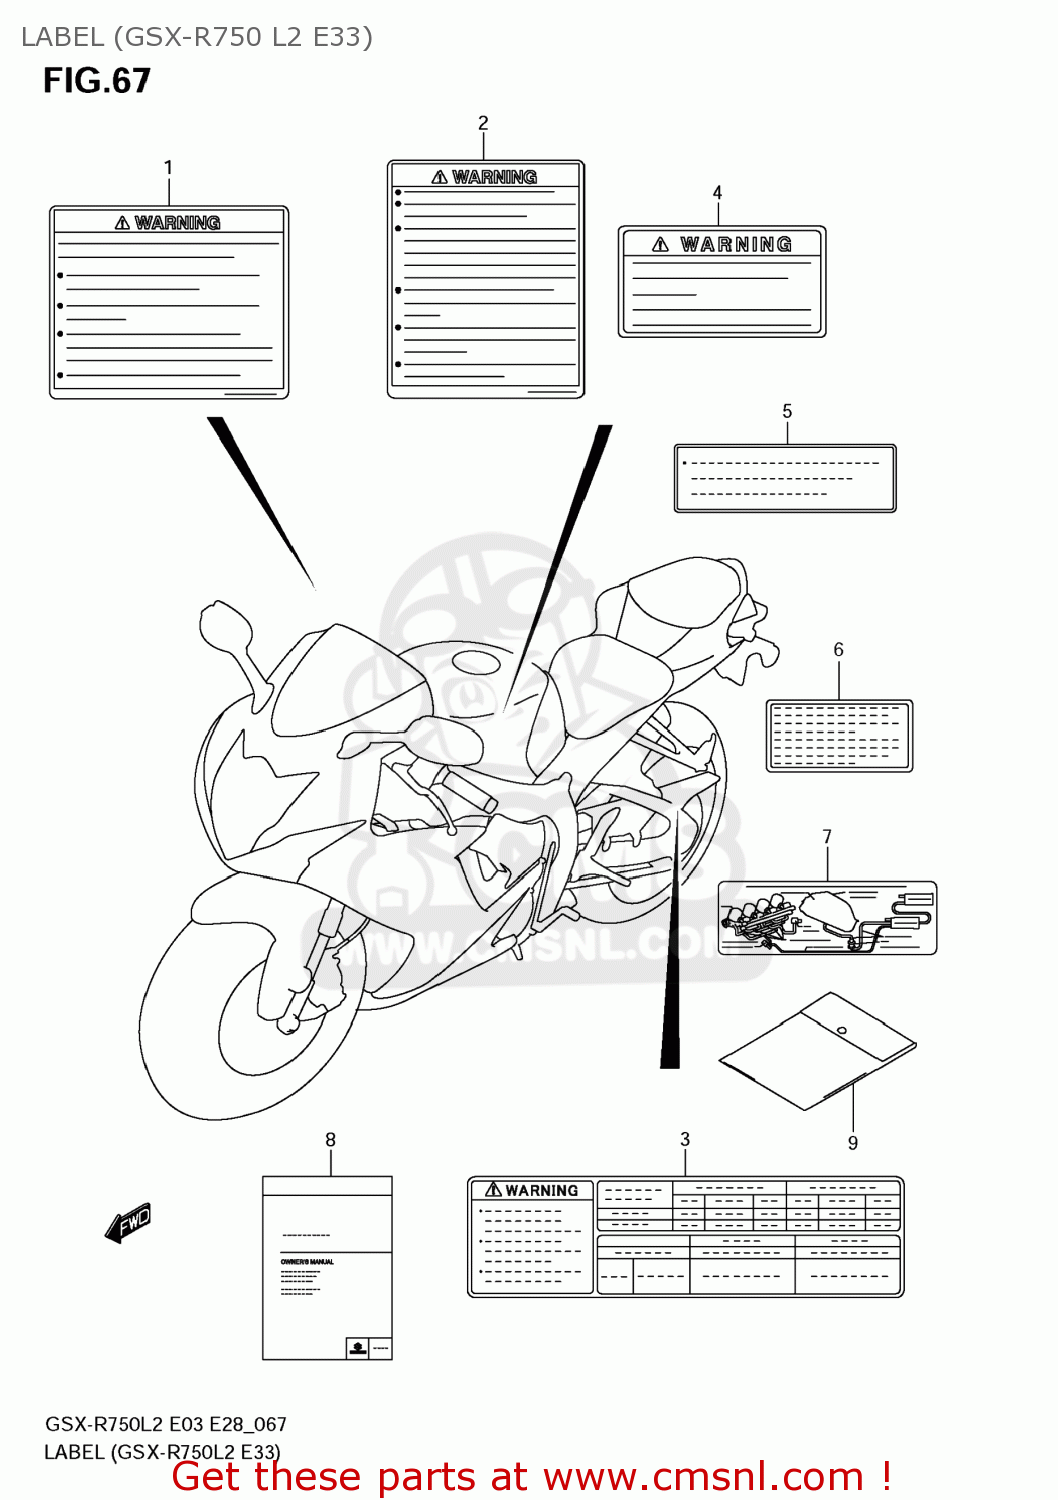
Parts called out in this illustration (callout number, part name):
1	LABEL,GENERAL WARNING
2	LABEL,SCREEN
3	LABEL,TIRE INFORMATION
4	LABEL,WARNING STEERING
5	LABEL,FUEL INFORMATION
6	LABEL,MANUAL NOTICE
7	LABEL,VACUUM HOSE ROUTING
8	MANUAL,OWNER'S
9	BAG,OWNER'S MANUAL
